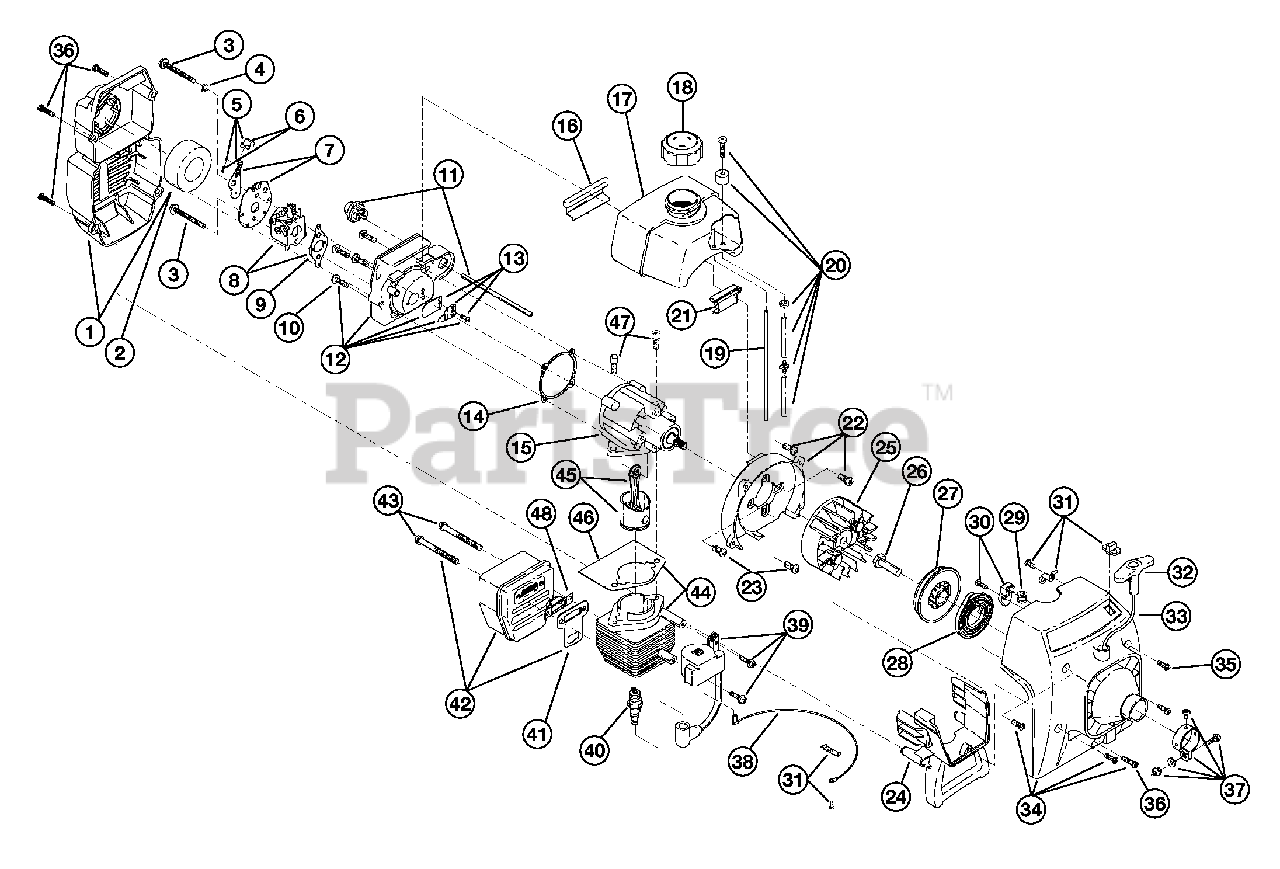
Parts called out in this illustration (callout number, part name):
1	Air Cleaner/Muffler Cover Assembly
2	Air Cleaner Filter
3	Carburetor Mounting Screw Assembly
4	Wavey Washer
5	Choke Lever Assembly
6	Choke Knob and Screw
7	Choke Lever & Plate
8	Carburetor Assembly
9	Carburetor Gasket
10	Carb Mount Screw
11	Primer and Hose Assembly
12	Carb Mount Assembly
13	Reed Assembly
14	Carburetor Mount Gasket
15	Crank Case Service Assembly
16	Rear Mounting Pad
17	Fuel Tank Assembly
18	Fuel Cap Assembly
19	Fuel Return Line
20	Fuel Line Assembly
21	Front Mounting Pad
22	Shroud Assembly
23	Shroud Screw
24	Shroud Extension and Stand
25	Flywheel Assembly
26	Square Nut Drive
27	Recoil Pulley Assembly
28	Recoil Spring
29	Rope Guide
30	Pulley Retainer Assembly
31	Switch Assembly
32	Pull Handle
34	Starter Housing Assembly
35	Housing Screw
36	Cover Screw
37	Upper Clamp Assembly
38	Wire Lead
39	Module Assembly
40	Spark Plug
41	Exhaust Gasket
42	Muffler Assembly
43	Muffler Mounting Bolt Assembly
44	Cylinder Assembly
45	Piston and Rod Assembly
46	Cylinder Gasket
47	Cylinder Bolt
48	Spark Arrestor
